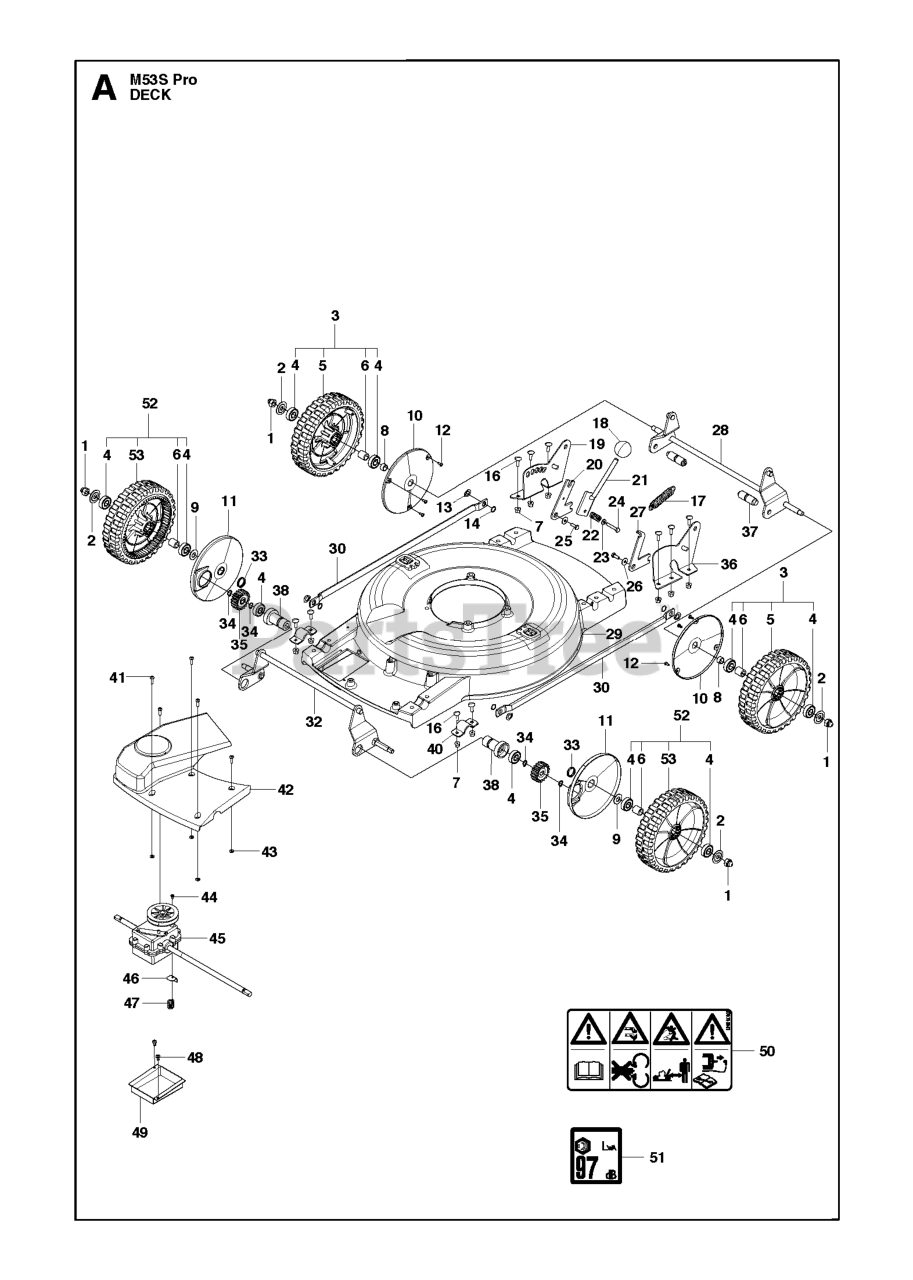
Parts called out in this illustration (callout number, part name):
1	NUT M53S / M48S
3	WHEEL PRO HUSQVARNA
4	BALL BEARING 6201-2RS/C3 W10
5	WHEEL ASSY PRO HUSQVARNA
6	SPACER PRO
7	LOCKING NUT FLANGE
8	SPACER M53 L=9
9	SPACER WASHER M53S / M48S
10	SHIELD PRO
11	SHIELD PRO
13	RING M53S / M48S
14	RETAINING RING
17	SPRING M53 / M48
18	BALL M53 / M48
20	LINK ARM M53
21	LEVER ASSY M53 / M48 M48
22	SPRING M53 / M48
23	WASHER
24	BOLT FLANGE
25	BOLT FLANGE M6X16
26	WASHER - 26X6.5X1.6
28	AXLE ASSY M53 PRO
29	CHASSIS M53S HUSQVARNA WITH CR
32	AXLE ASSY M53S PRO
33	SPRING M53 / M48
35	PINION PRO
37	SHAFT M53 / M48
38	SHAFT M53S / M48S
42	FRONT COVER M53S HUSQVARNA
44	SCREW RXS B8X9.5
45	GEAR BOX M53S
46	BRACKET M53 / M48
47	SPRING M53S / M48S
48	SCREW ITXPANTT M5X10 ZPB (A00
52	WHEEL PRO, DRIVING HUSQVARNA
53	WHEEL ASSY PRO, DRIVING HUSQVA
